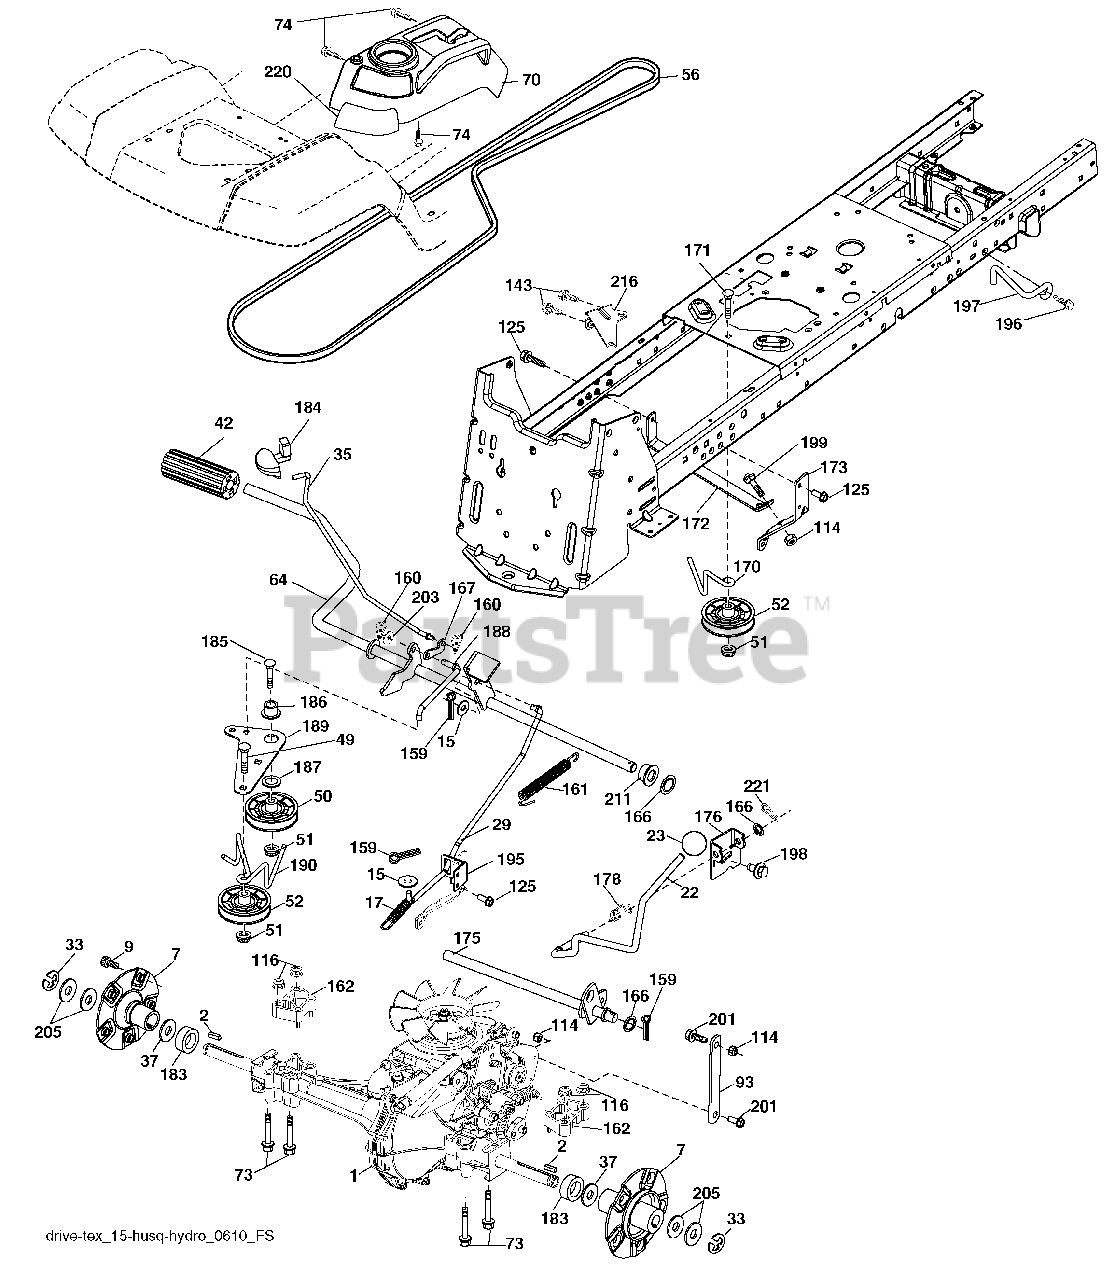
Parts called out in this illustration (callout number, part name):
2	Key 1/4 x 2.5
7	Hub Asm. Wheel
9	Bolt Hub Wheel
15	Washer 13/32 x 13/16 x 16 Ga.
17	Spring, Brake
22	Shifter Rod
29	Rod, Brake
35	Rod, Brake, Park
42	Cover, Foot Pedal
50	Pulley Idler Flat
51	Lock Nut 3/8-16
52	Idler V-Groove 910" Offset
56	V-Belt, Drive
64	Shaft Asm. Pedal Brake Control
70	Control Asm.
73	Bolt Hex Flghd 5/16-18 x 3.75
74	Screw 1/4 x 1/2
93	Link Shift
114	Nut Lock Hex w/Insert 5/16-18 unc
116	Nut Lock Hex Flange 5/16-18
125	Screw 5/16-18 x 3/4
143	Screw Thdrol 5/16-18 x 1/2
159	Pin Cotter 1/8 x 3/4
160	Retainer Clip
161	Spring, Return, Clutch
162	Spacer Trans.
166	Nut Push .625
167	Latch Brake Parking
170	Keeper Belt Centerspan
172	Strap Torque LH
173	Strap Torque RH
175	Shaft Asm Shift
176	Arm, Shift Rod
178	Spring Shift
183	Spacer Split
184	Handle Parking Brake
185	Bolt Rdhd Sqnk 3/8-16 x 2-1/2
186	Spacer Retainer
187	Washer
188	Link Clutch Ground Drive
189	Bellcrank Ground Drive
190	Keeper Bellcrank Ground Dr.
195	Bracket Rod Brake
196	Screw 3/8-16 x 1
197	Bracket Clutch Anti-Rotation
198	Screw 7/16-14 x 7/8 Flghd
199	Bolt Rdhd Sqnk 5/16-18 unc x 1
201	Bolt Shoulder 5/16-18 unc
203	Washer 11/32 x 11/16 x 16 Ga.
216	Bracket Pulley Idler
220	Reflector RH
221	Retainer Spring Clip Handle
